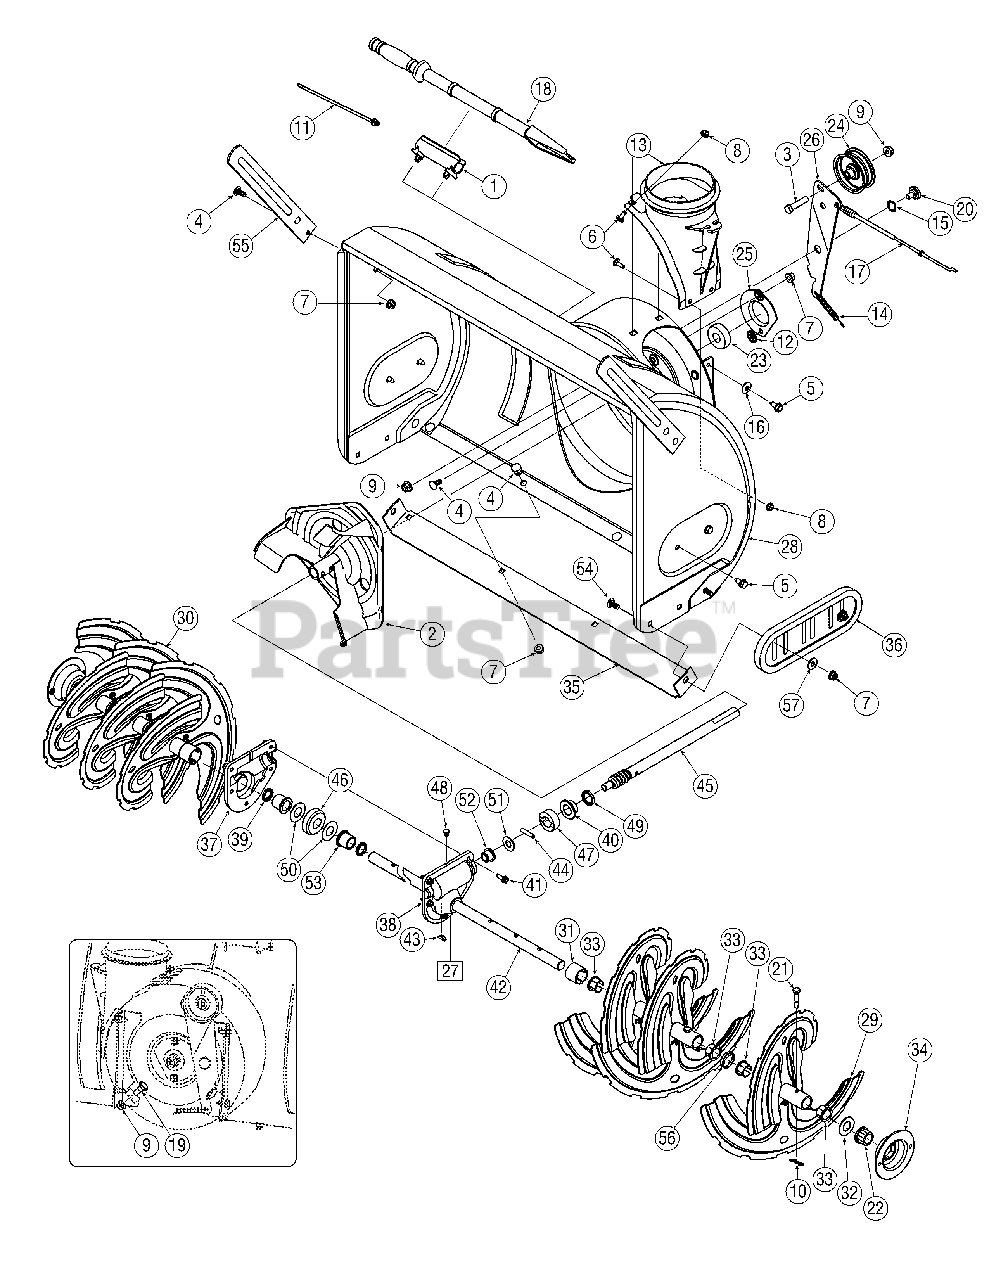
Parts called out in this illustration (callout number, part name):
1	Snow Removal Tool Mount
2	Impeller Assembly, 12" Dia.
3	Hex Screw, 3/8-16, 1.75, Gr5
4	Bolt, Carriage, 5/16-18, .750 Gr1
5	Screw, 5/16-18, 0.750
6	Screw, Carriage, 1/4-20, .750, Gr5
7	Nut, Flange Lock, 5/16-18, Nylon
8	Nut, Flange Lock, 1/4-20, Nylon
9	Nut, Flange Lock, 3/8-16, Nylon
10	Cotter Pin, Bow-tie
11	Cable, Tie, 3/16 x .05 x 7.4
12	Nut, Push-on, .25 Dia
13	Chute, Adapter 5" Dia
14	Spring, Extension, .38 OD x 4.59
15	Washer, Wave, .625 x .885 x .015
16	Washer, Bell, .340 x .872 x .060
17	Clutch Cable, Auger, 47.23"
18	Snow Removal Tool
19	Screw, Shoulder, .498 x .34, 3/8-16
20	Screw, Shoulder, .625 x .17, 3/8-16
21	Shear Pin, .25 x 1.50
22	Bearing, Hex Flange x .75 ID
23	Bearing, Ball, .75 ID x 1.85 OD
24	Flat Pulley, Idler, 2.75 OD
25	Housing, Bearing, 1.85 ID
26	Bracket, Auger Idler w/ Brake
27	Gearbox Assembly, Auger, 30"
28	Housing Assembly, Auger 30"
29	Spiral Assembly, LH
30	Spiral Assembly, RH
31	Spacer, 1.25 OD x .75 ID x 1.00
32	Washer, Flat, .76 x 1.49 x .06
33	Bushing, Flange, .80 ID x .91 OD
34	Housing, 1" Hex Bearing
35	Shave Plate, 2.25 x 29.66
36	Slide Shoe, Deluxe Polymer
36	Deluxe Polymer Reversible Shoe Kit
37	Housing, Auger, RH Reduced
38	Housing, Auger, LH Reduced
39	Seal, Oil, .750 x 1.00 x .125
40	Bearing, Flange, .75 x 1.0 x .59
41	Screw, Self-tapping, 1/4-20, 0.750
42	Axle, Auger, 30"
43	Key, Hi-pro 3/16 x 5/8
44	Pin, Dowel, .25 OD x 1.2
45	Shaft, Worm .75 OD
46	Gear, Worm 20T
47	Collar, Thrust
48	Plug, 1/4 x .437
49	Seal, Oil, .75 x 1 x .131
50	Washer, Flat, .760 ID x 1.5 OD
51	Washer, Flat, .51 x 1.12
52	Bearing, Flange, .75 x 1.0 x .925
53	Bearing, Flange, .75 x 1.00 x .975
54	Scr., Crg., 5/16-18 x 1.00
55	Drift Cutter
56	Spacer, 1.25 OD x .75 ID x 3/16
57	Washer, Flat, .349 x .879 x .063
